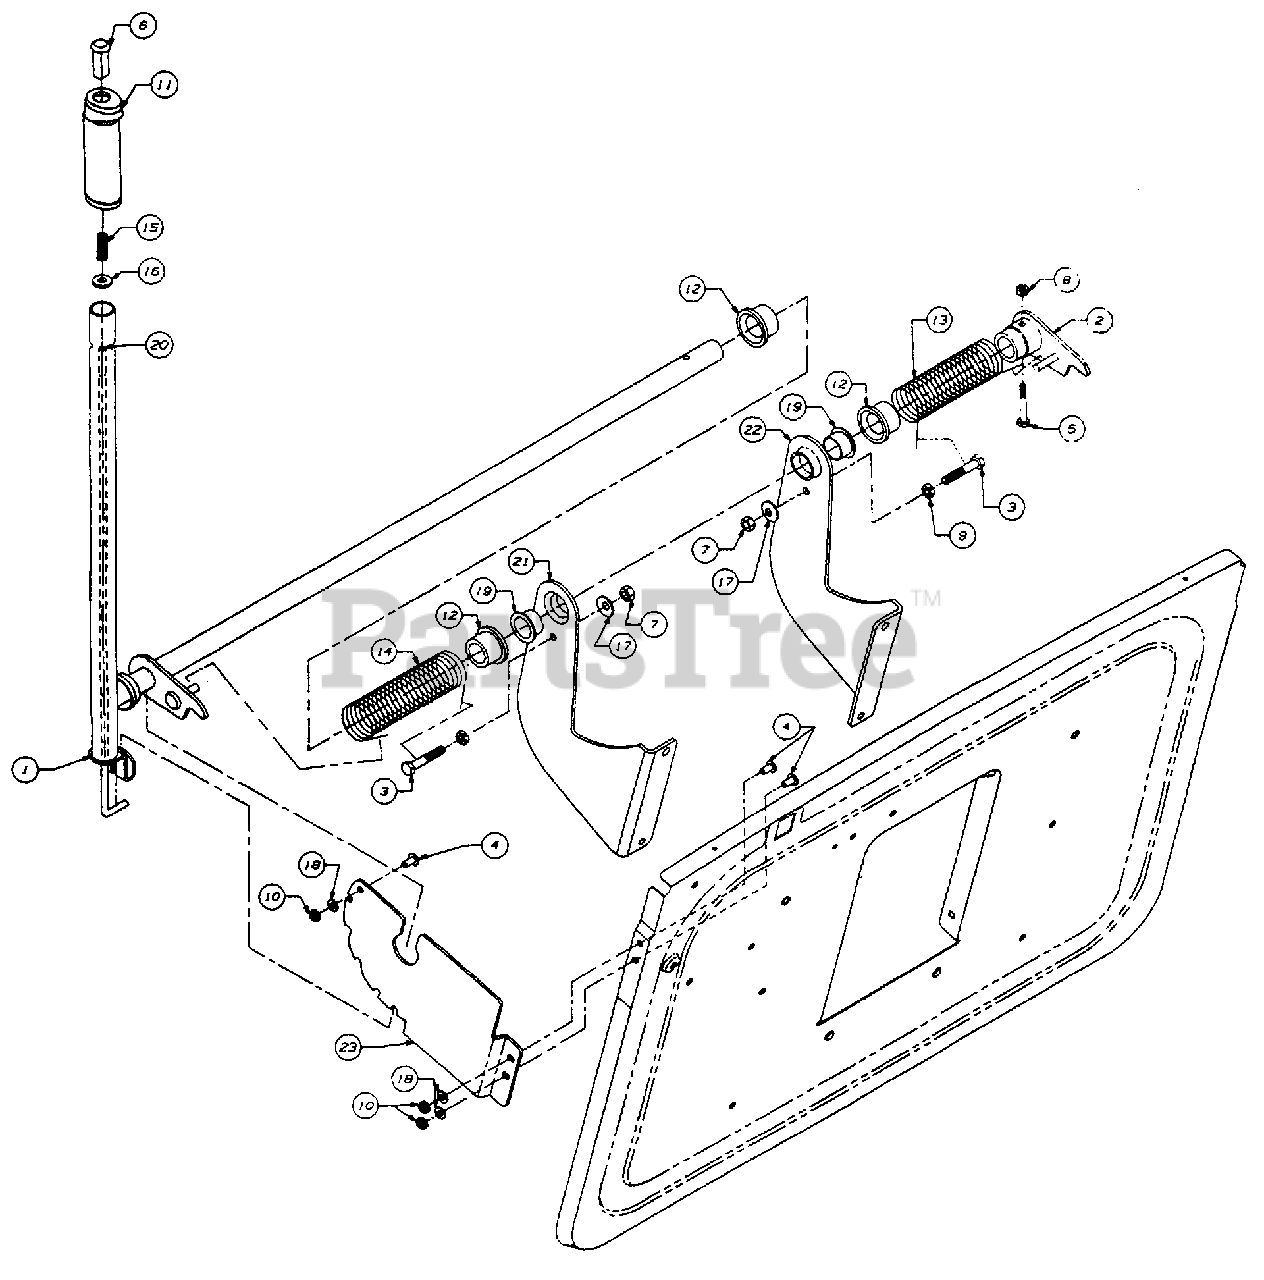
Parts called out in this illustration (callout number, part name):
3	Hex Bolt 5/16-24 x 1.75" Lg. (Gr. 5)
4	Pan Hd. Mach. Scr. 1/4-20 x .5" Lg.
5	Hex bolt 1/4-28 x 1.75" Lg. (Gr. 5)
6	Handle Button
7	Hex Nut 5/16-24 Thd.
8	Hex L-Nut 1/4-28 Thd.
9	Hex Jam Nut 5/16-24 Thd.
10	Hex Ins. L-Nut 1/4-20 Thd.
12	Spring Retainer
13	Torsion Spring - L.H.
14	Torsion Spring - R.H.
15	Comp. Spring
16	Fl-Wash. .312" I.D. x .75" O.D.
17	Bell-Wash. .34" I.D. x .87" O.D.
18	L-Wash. 1/4" I.D.
19	Flange Bearing .88" I.D.
